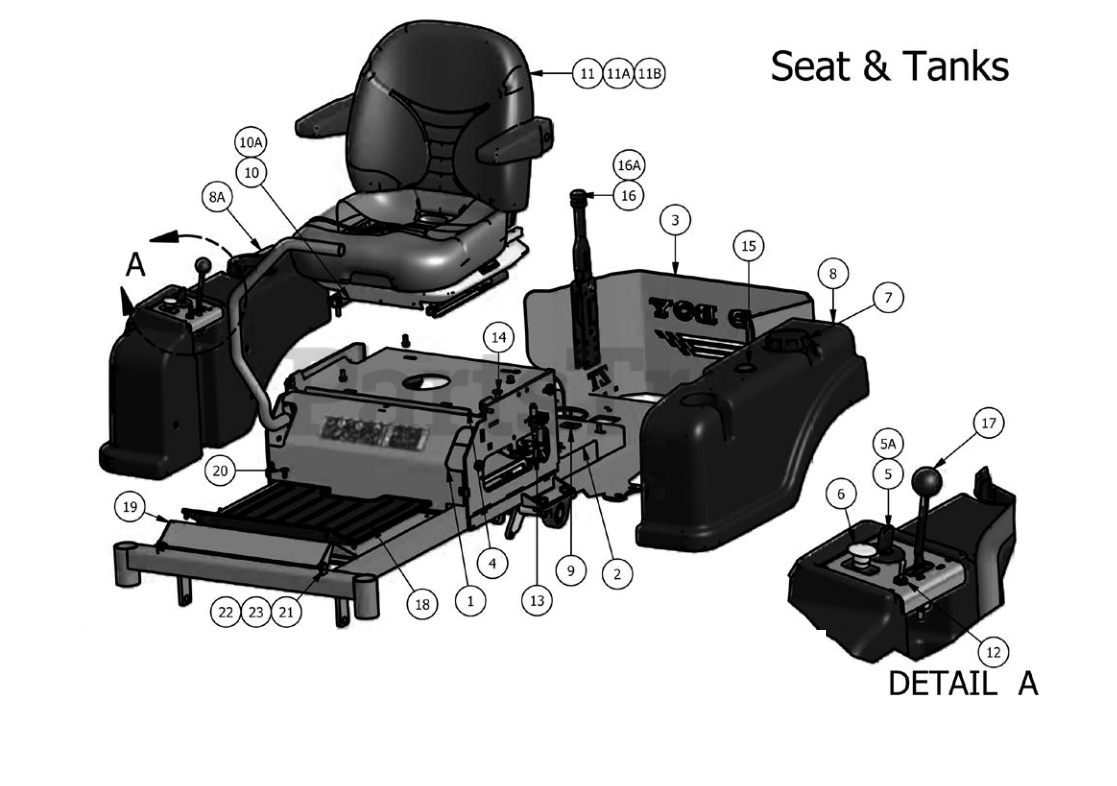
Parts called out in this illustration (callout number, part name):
1	Cooler Cover
3	ZT Rear Plate
4	ZT Seat Plate
5	Ignition Key
6	PTO Engager
8	Left Tank for all CZT and 60" ZT
8A	Right Tank for all CZT and 60" ZT
9	Tachometer
10	Seat Safety Switch
10A	Seat Safety Switch Pigtail
11	Seat Assembly for all CZT and 60" ZT
11A	Seat Assembly for 50" 26HP ZT
11B	Suspension Seat (Upgrade, and Shown)
13	Brake Cable
15	Fuel Gauge
16	Hand Brake
16A	Safety Switch
18	Zt Floorboard Mat
19	ZT Floor Panel
20	Ratchet Fastener-Floorboard
21	1/4" x 3/4" Carriage Bolt
22	1/4" Nylock Nut
23	.360 ID Plastic Washer
